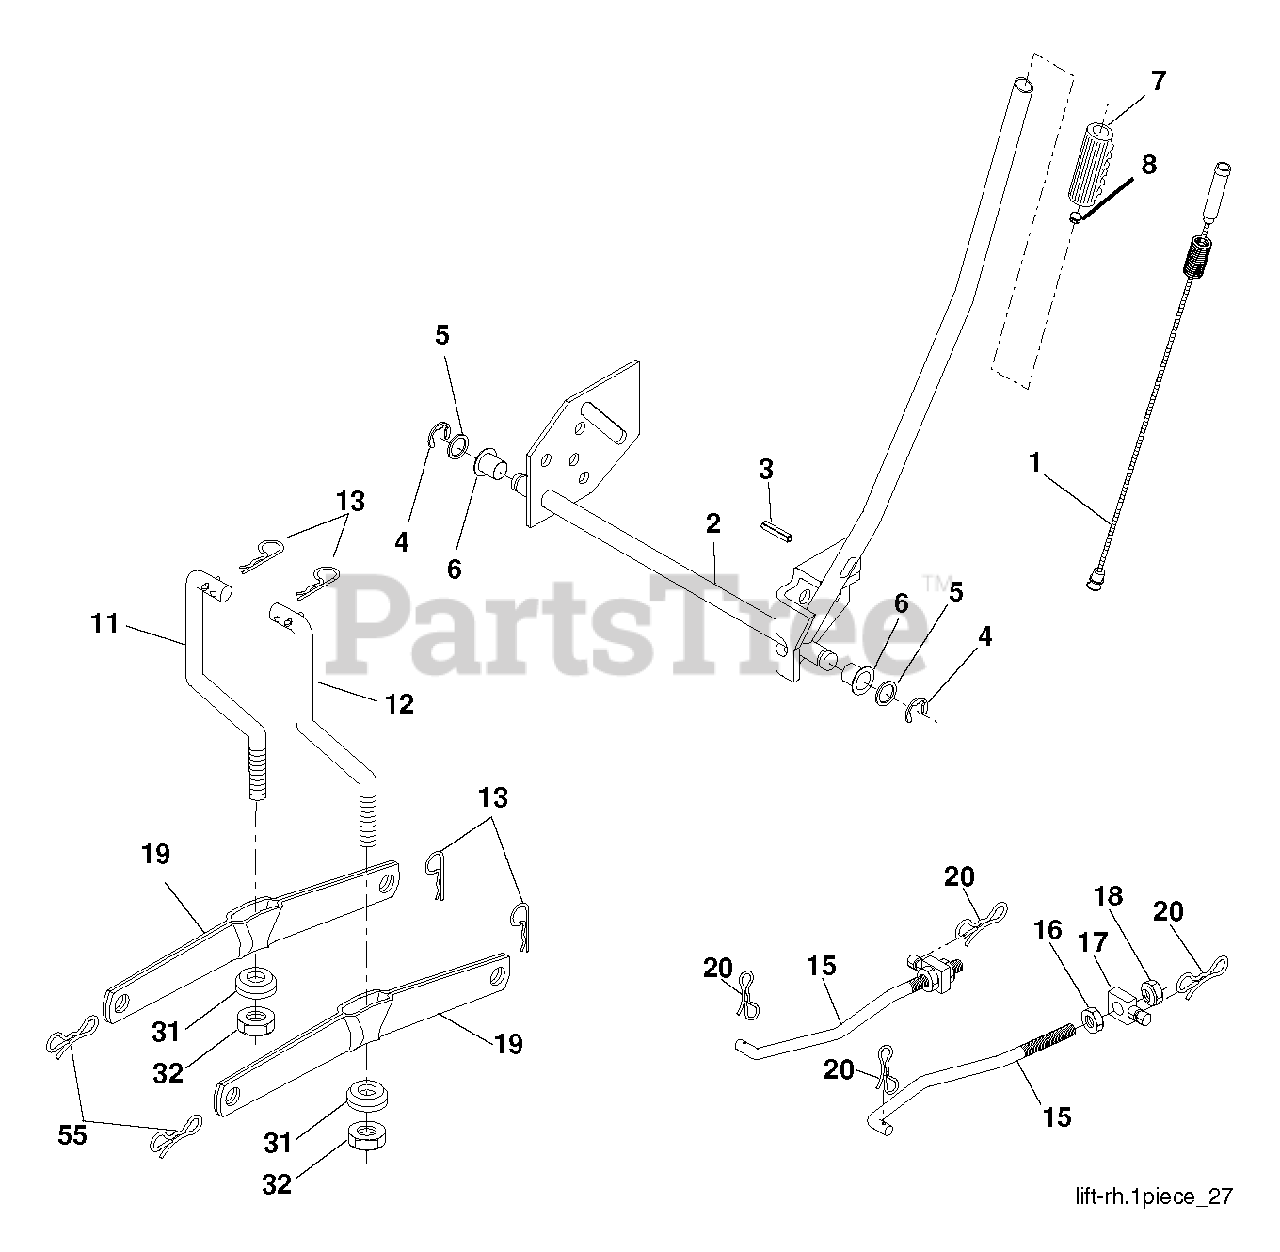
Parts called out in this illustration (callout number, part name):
4	RETAINING RING LT
6	BEARING.NYLON
7	GRIP
11	LINK LIFT LH
12	LINK LIFT RH
13	RETAINER-SPRNG RB
15	LINK.SUSPENSION.FRONT
16	NUT
18	NUT
19	ARM.REAR.SUSPENSION
20	PIN.COTTER.7/16.BOW TI
31	BEARING.PIVOT.LIFT
32	NUT CROWNLOCK 3/8-24
55	PIN.COTTER.5/16.BOW TI
